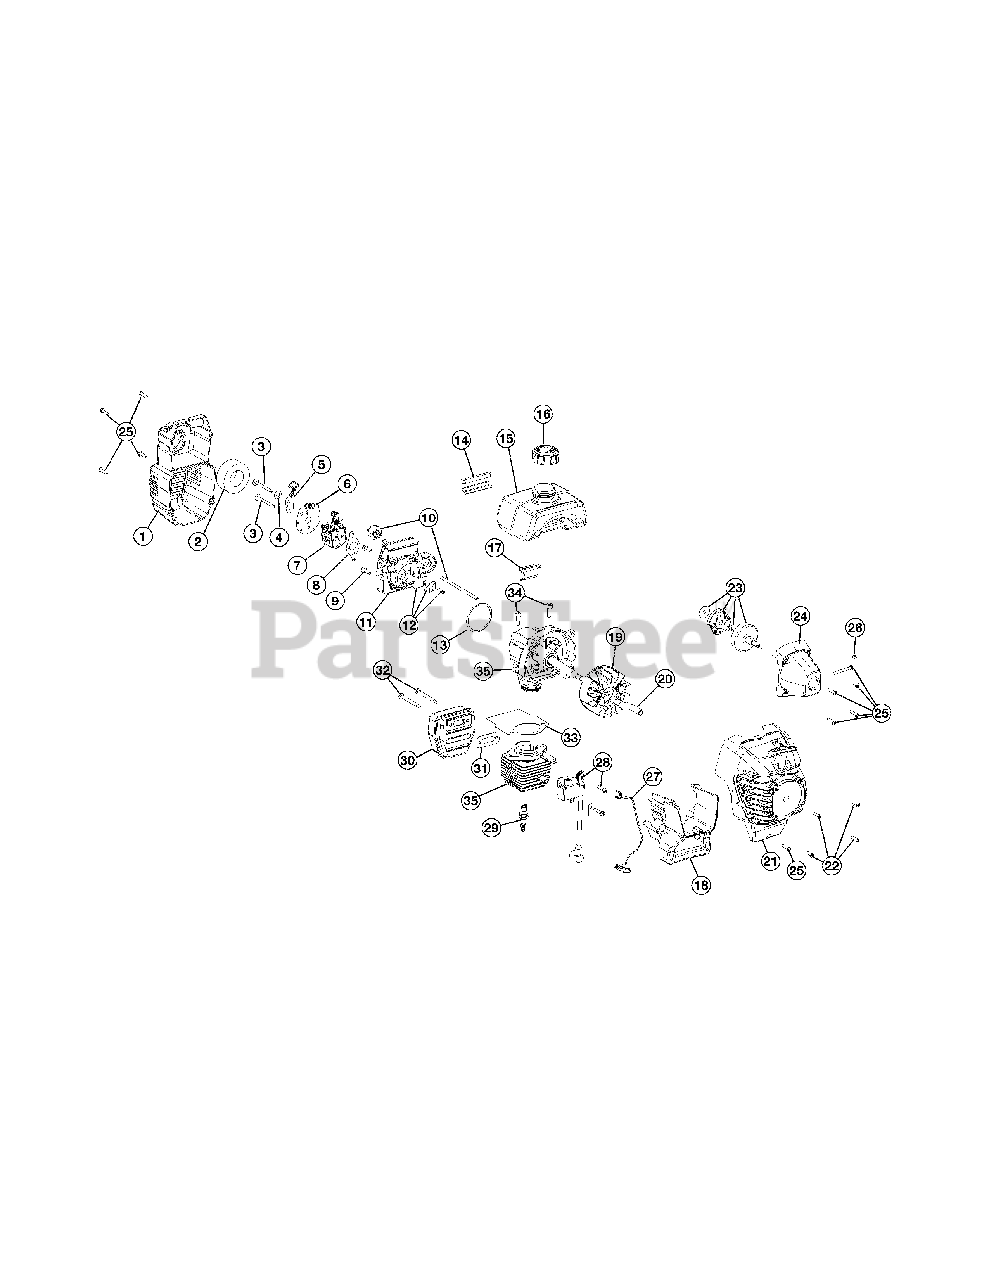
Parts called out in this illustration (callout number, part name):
1	Air Cleaner Cover Assembly (includes 2 & 25)
2	Air Cleaner Filter
3	Carburetor Mounting Screw Assembly
4	Wavey Washer
5	Choke Lever Assembly
6	Choke Plate Assembly (includes 5)
7	Carburetor Assembly (includes 8)
8	Carburetor Gasket
9	Carb Mount Screw
10	Primer & Hose Assembly
11	Carb Mount Assembly (includes 9, 12 & 13)
12	Reed Assembly
13	Carburetor O-Ring
14	Rear Mounting Pad
15	Fuel Tank Assembly (includes 16)
16	Fuel Cap Assembly
17	Front Mounting Pad
18	Shroud Extension & Stand (includes 25)
19	Flywheel Assembly
21	Starter Housing Assembly (includes 22 & 25)
22	Housing Screw
23	Clutch Rotor Assembly
24	Clutch Cover Assembly (includes 25 & 26)
25	Cover Screw
26	Anti-Rotation Screw
27	Wire Leads and Sleeve
28	Module Assembly
29	Spark Plug
30	Muffler Assembly (includes 31 & 32)
31	Exhaust Gasket
32	Muffler Mounting Bolts
33	Cylinder Gasket
34	Cylinder Bolt
35	Short Block Assembly (includes 9, 29, 33 & 34)
